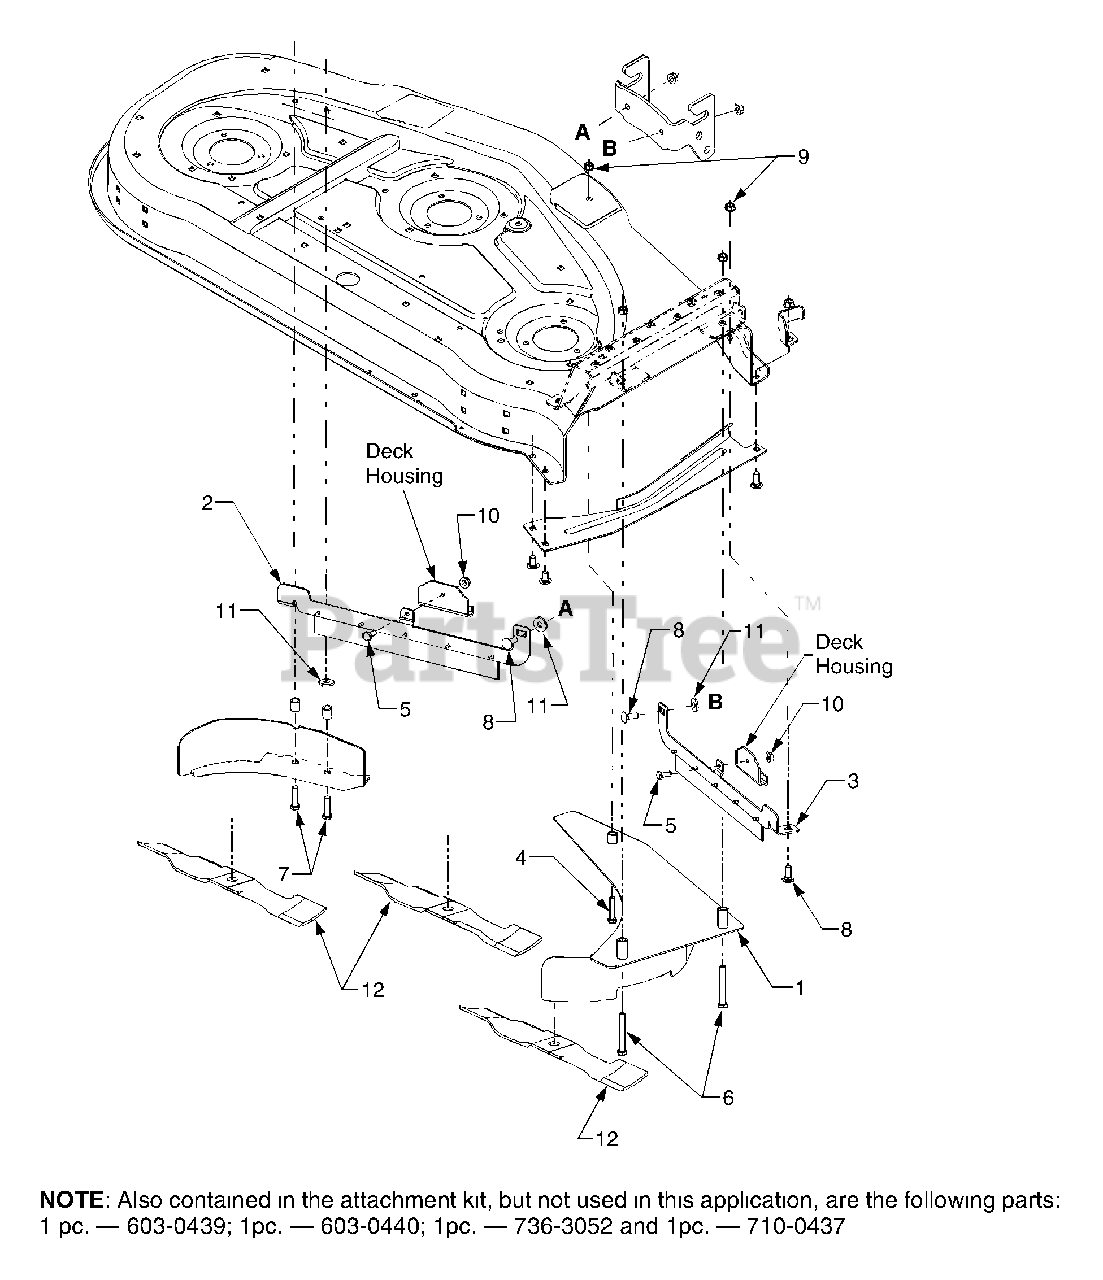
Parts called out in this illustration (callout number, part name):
3	Bracket Ass'y, Rubber Flap/Mtg RH
4	Screw, Hex Cap, 3/8-16 x 1.5 GR5
5	Screw, Hex Cap, 1/4-20 x .62 GR5
6	Screw, Hex Cap, 3/8-16 x 2-1/4 GR5
7	Screw, Hex Cap, 3/8-16 x 1-3/4 GR5
8	Bolt, Carriage, 3/8-16 x 1.0 GR5
9	Nut, Hex Flange Lock, 3/8-16
10	Nut, Hex Flange Lock, 1/4-20
11	Washer, Flat, .406 X 1.0 x .105
12	Blade, Mulching, 16.5 Lg
